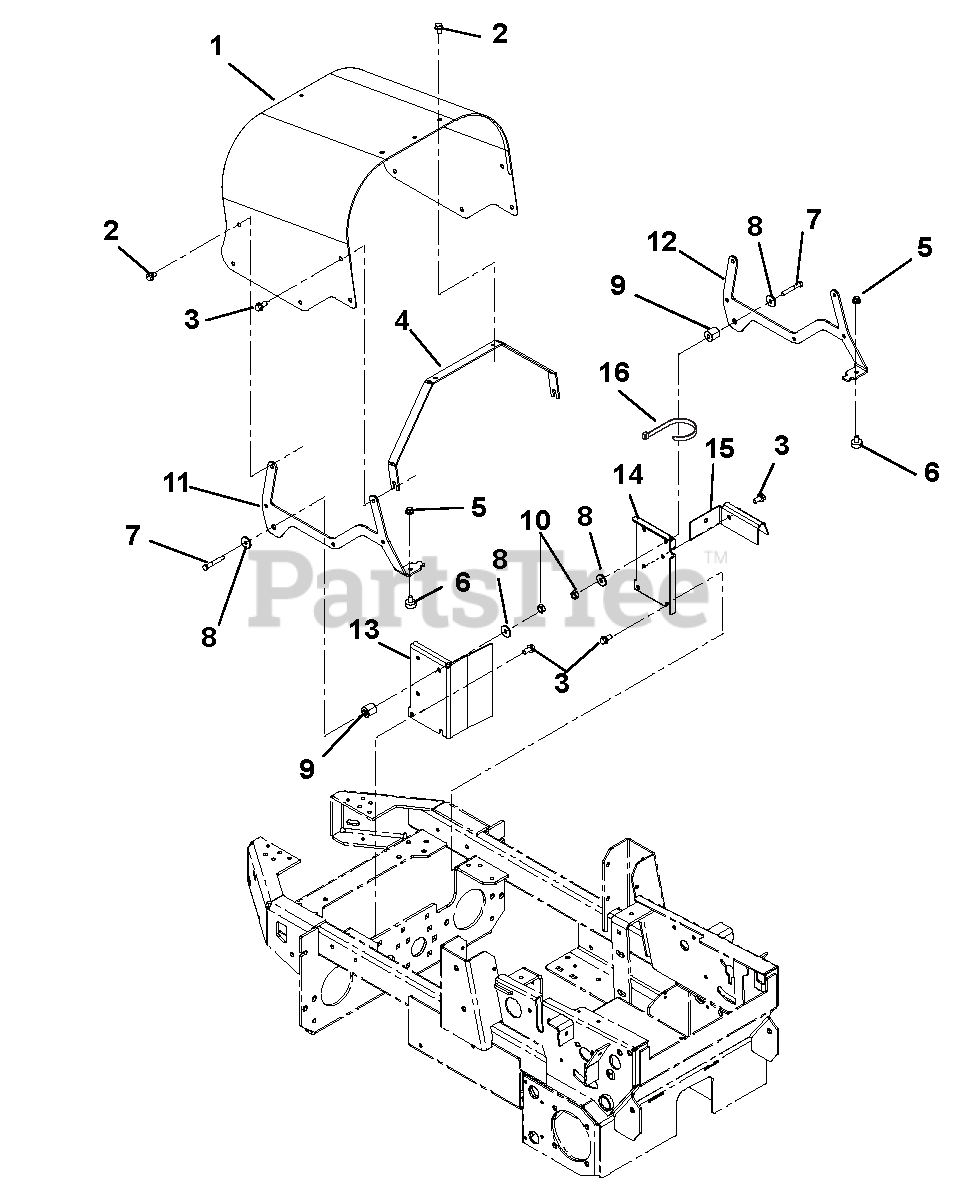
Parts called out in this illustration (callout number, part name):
1	HOOD, OUTFRONT
2	@SCR-TAP .38-16X.50 HWH TR YWZ
3	@SCR-TAP .38-16X.75 HWH TR YWZ
4	SUPPORT, LATERAL HOOD
5	NUT-SPNLK-FLG .312-18 YWZC
6	BUMPER, RUBBER
7	@BLT-HEX .31-18X2.25 GR5 YWZC
8	WSHR-FL-STL .344X1.125X.135
9	SPCR, FLG .32X.49X.192X1.00
10	NUT-LK-CTR .31-18 YWZC
11	BRACKET, LH HOOD
12	BRACKET, RH HOOD
13	BRACKET, HOOD SUPPORT #2 (OFM)
14	BRACKET, HOOD SUPPORT #1 (OFM)
15	COVER, WIRE
16	CABLE TIE LG 5-1/2
